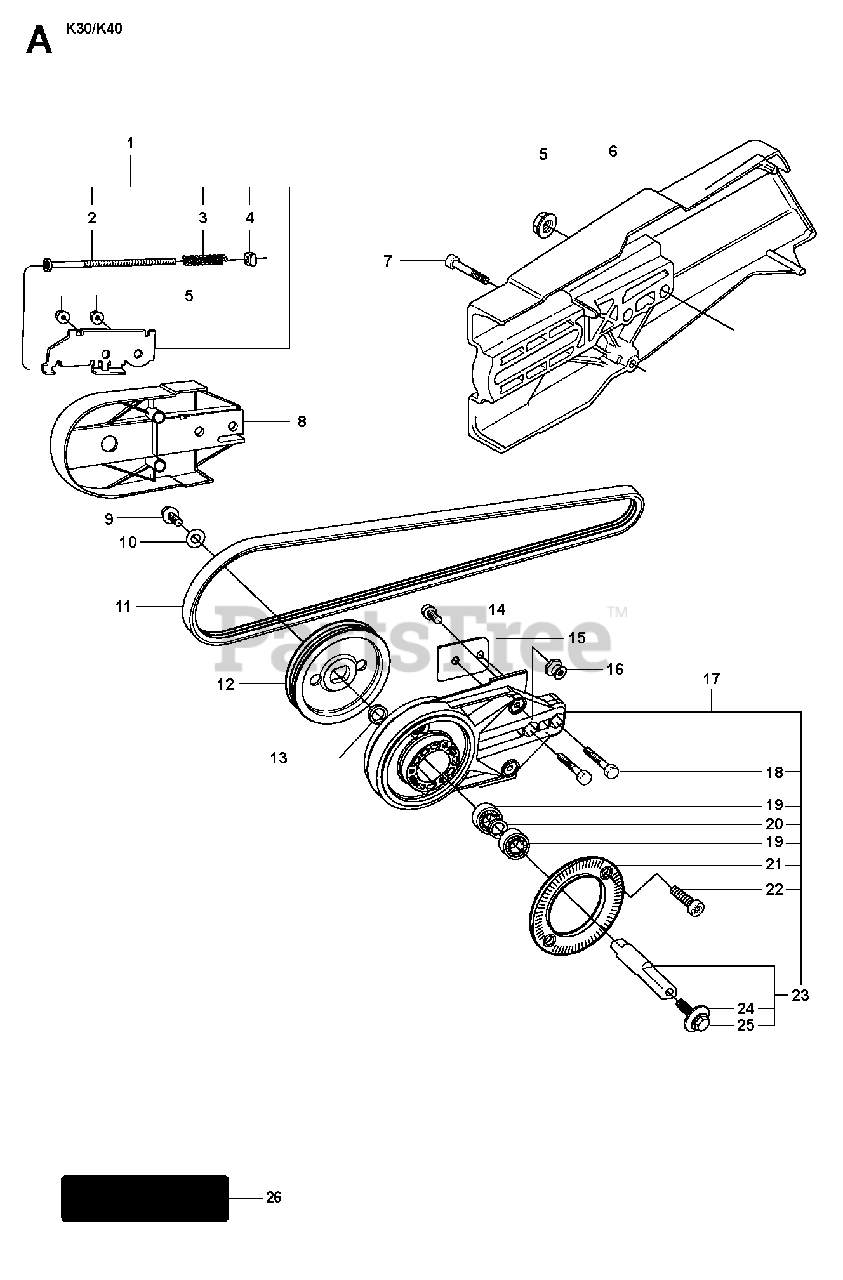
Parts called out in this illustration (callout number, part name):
1	BELT TENSIONER ASSYIncl. 2 - 4
7	SCREW ITXSCM
14	SCREW ITXSCM
16	TORSION STOP
17	BEARING HOUSING ASSYIncl. 18 - 23
19	BALL BEARING
22	SCREW ITXSCM
26	LABELJapan only
